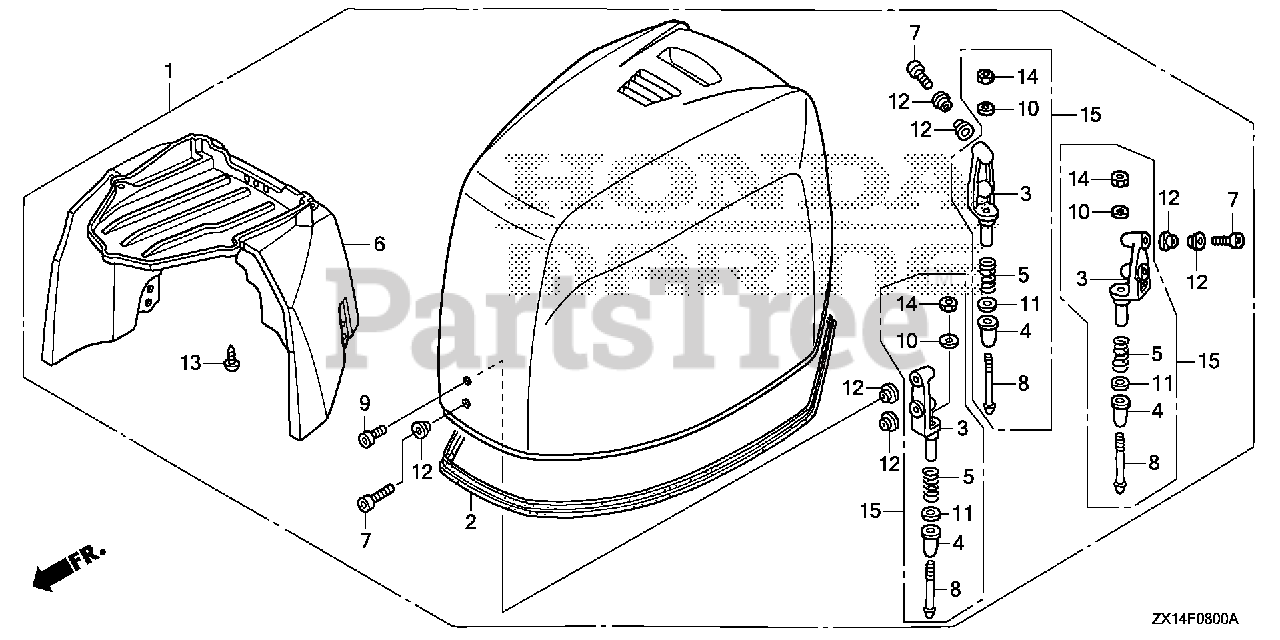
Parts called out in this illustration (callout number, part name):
1	COVER, ENG *NH282MU*
2	SEAL, ENGINE COVER
3	BRACKET, HOOK
4	DAMPER, HOOK
5	SPRING, LOCK ADJUSTER
6	GUIDE, ENGINE COVER AIR
7	BOLT, SOCKET (6X20)
8	BOLT, COVER LOCK
9	BOLT, SOCKET (6X16)
10	WASHER, PLAIN (6MM) Use from Frame SN 4800713.
11	WASHER, PLAIN (12MM)
12	COLLAR, DISTANCE (6.5X9X3)
13	SCREW, TAPPING (4X12)
14	NUT, HEX. (6MM)
15	HOOK KIT, COVER
